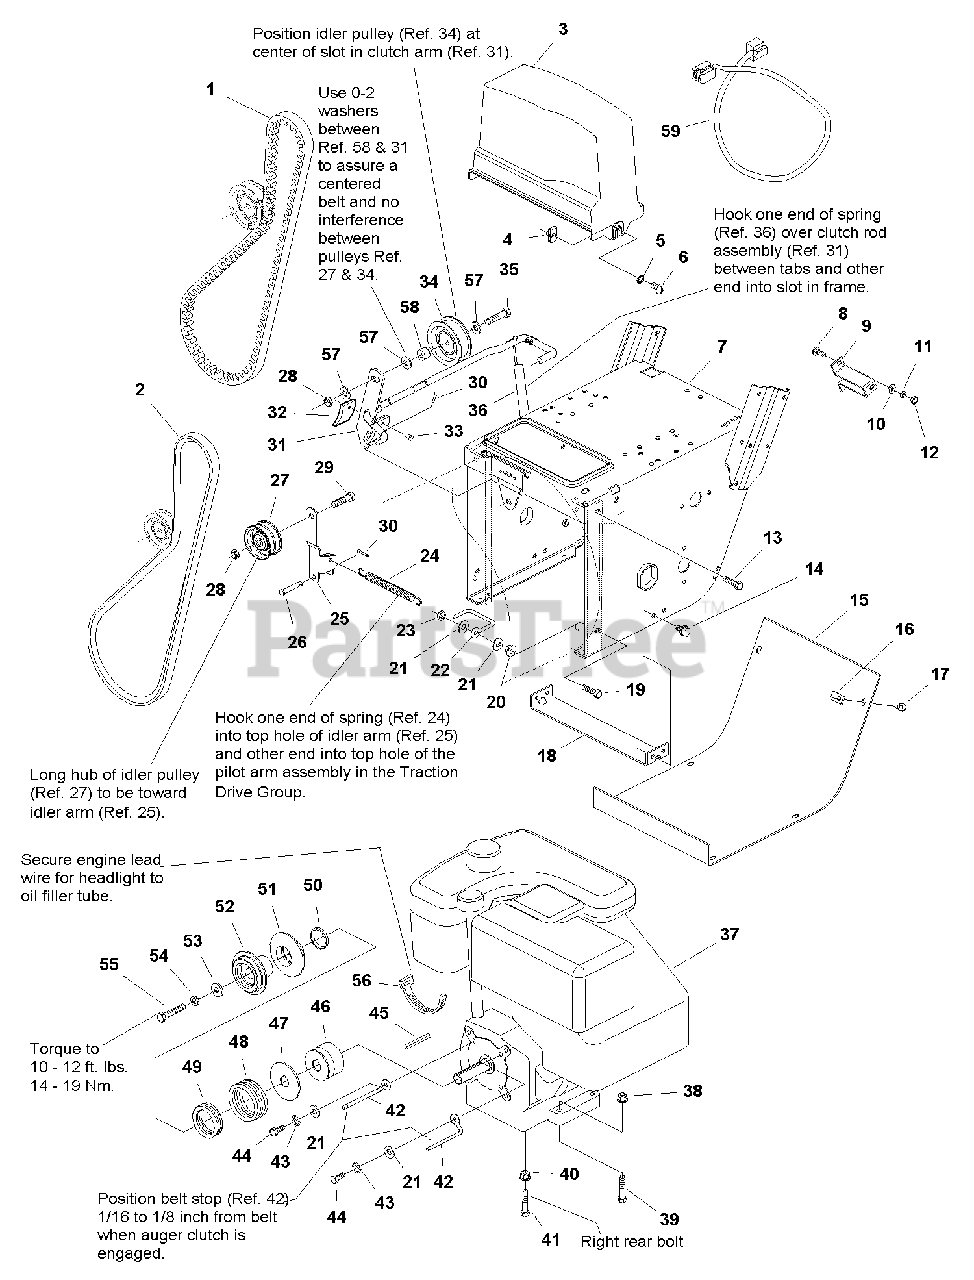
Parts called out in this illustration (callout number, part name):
1	BELT, Traction
2	BELT, Auger Drive
3	GUARD, Belt
4	NUT, Speed, 5/16-18
5	LOCKWASHER, Ext. Tooth, 5/16
6	SCREW, Truss Head, 5/16-18 x 3/4
7	FRAME, Main
8	CARRIAGE BOLT, 1/4-20 x 3/4
9	SUPPORT, Clutch Cable
10	WASHER, 1/4
11	LOCKWASHER, Spring, 1/4
12	NUT, Hex 1/4-20
13	CAPSCREW, Whizlock, 5/16-18 x 3/4
14	CAPSCREW, Taptite, 5/16-18 x 3/8
15	COVER, Bottom
16	NUT, Speed, 1/4-20
17	CAPSCREW, Taptite,1/4-20 x 1/2
18	SUPPORT, Tie Bar
19	CAPSCREW, Whizlock, 5/16-18 x 1-1/4
20	NUT, Hex, Whizlock, 5/16-18
21	WASHER,11/32 x 3/4
22	GUIDE, Belt
23	NUT, Hex, Centerlock, 5/16-18
24	SPRING, Idler
25	ARM, Idler, Traction
26	PIN
27	PULLEY, Idler
28	LOCKNUT, Jam, 3/8-16
29	CAPSCREW, Hex Head, 3/8-16 x 1-1/2
30	PlN,Cotter,1/8 x 3/4
31	CLUTCH ROD & BRAKE ASSEMBLY
35	CAPSCREW, Hex Head, 3/8-16 x 1-3/4
36	SPRING, Extension
38	NUT, Hex, 5/16-18, Black
39	CAPSCREW, Hex Head, 5/16-18 x 2, Black
40	NUT, Hex Flange, 5/16-18
41	CAPSCREW, Hex Head 5/16-18 x 2 G5
42	GUIDE, Belt
43	LOCKWASHER, 5/16
44	CAPSCREW, Hex Head, 5/16-24 x 3/4
45	KEY, Parallel, 3/16 x 13/16 x 7/8
46	PULLEY, Traction
47	WASHER, Thrust
48	SPRING, Compression
49	SPRING, Compression
51	PULLEY, Drive
52	PULLEY, Drive
53	WASHER,13/32 x 1
54	LOCKWASHER, Spring, 3/8
55	CAPSCREW, Hex Head, 3/8-24 x 2
56	TIE, Self Locking
57	WASHER, Flat,13/32
59	CORD, Electric, 3 Prong
